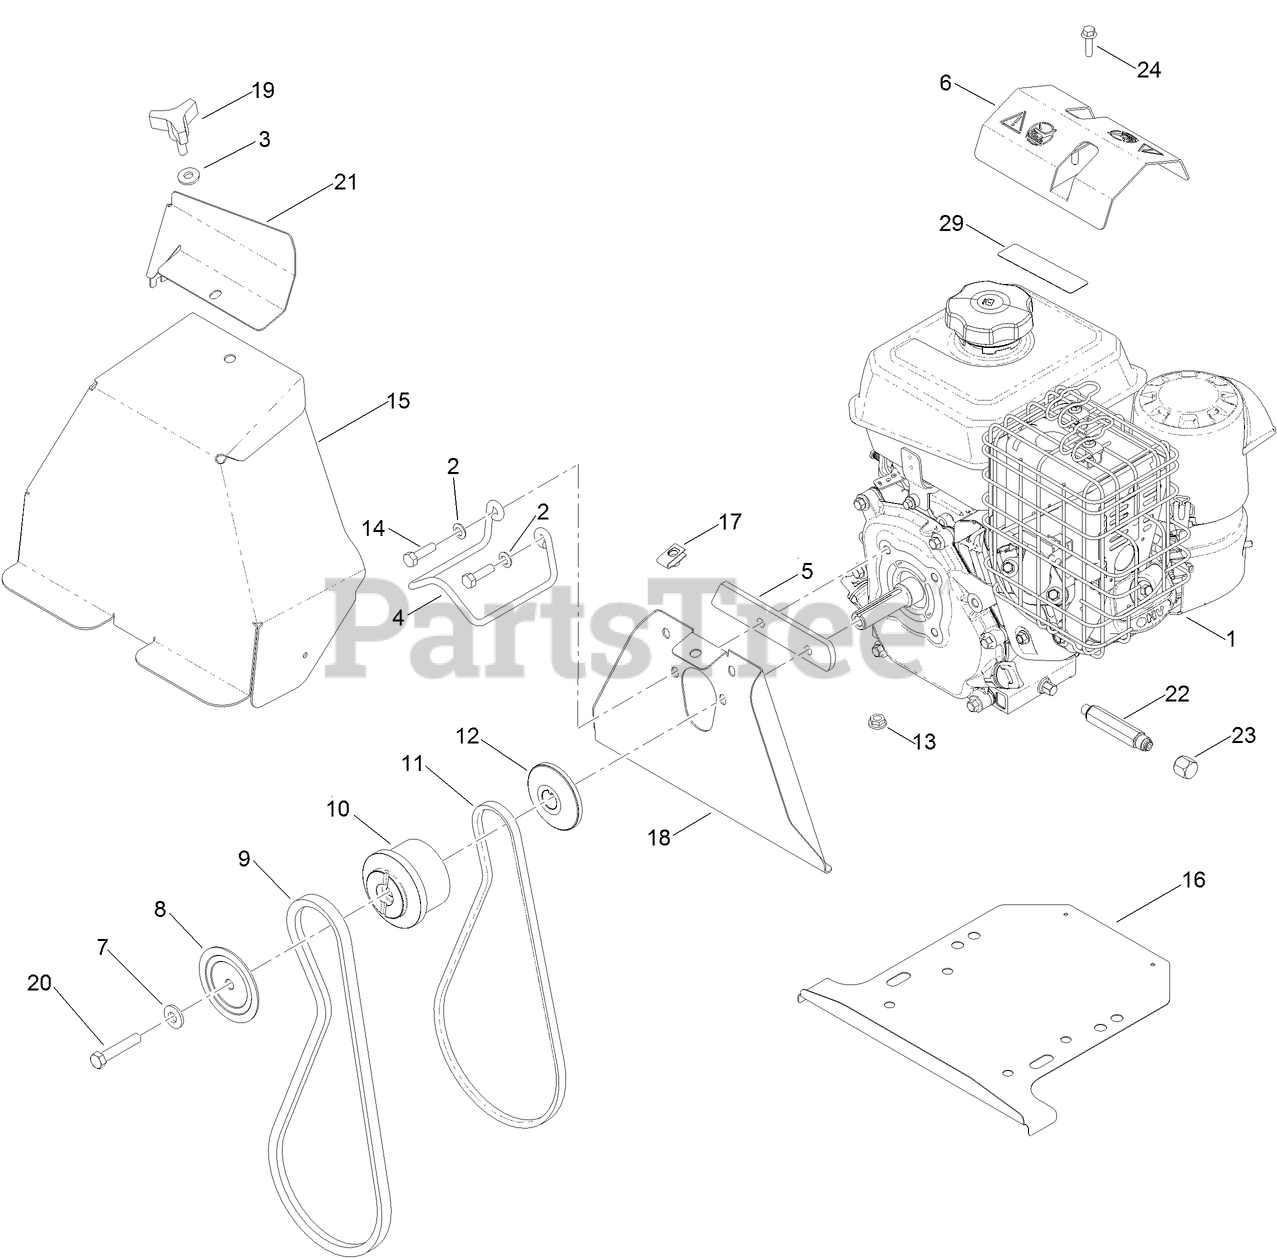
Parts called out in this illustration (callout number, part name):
2	WASHER-BELLEVILLE
3	WASHER-SPRING
4	GUIDE-BELT
5	SPACER-COVER, BELT
6	DEFLECTOR-DEBRIS, MUFFLER
7	WASHER-BELLEVILLE
8	SHEAVE-HALF, IMPELLER
9	Belt-Blower
10	PULLEY-ENGINE, CENTER
11	V BELT-TRACTION
12	SHEAVE-HALF, TRACTION
13	NUT-HF
14	SCREW-HH
15	COVER-BELT
16	SHIELD-DRIVE
17	NUT-U
18	COVER-BELT, BACK
20	SCREW-HH
21	SHIELD-ICE
22	ADAPTER
24	SCREW-HHF
29	DECAL-ARRESTER, SPARK
